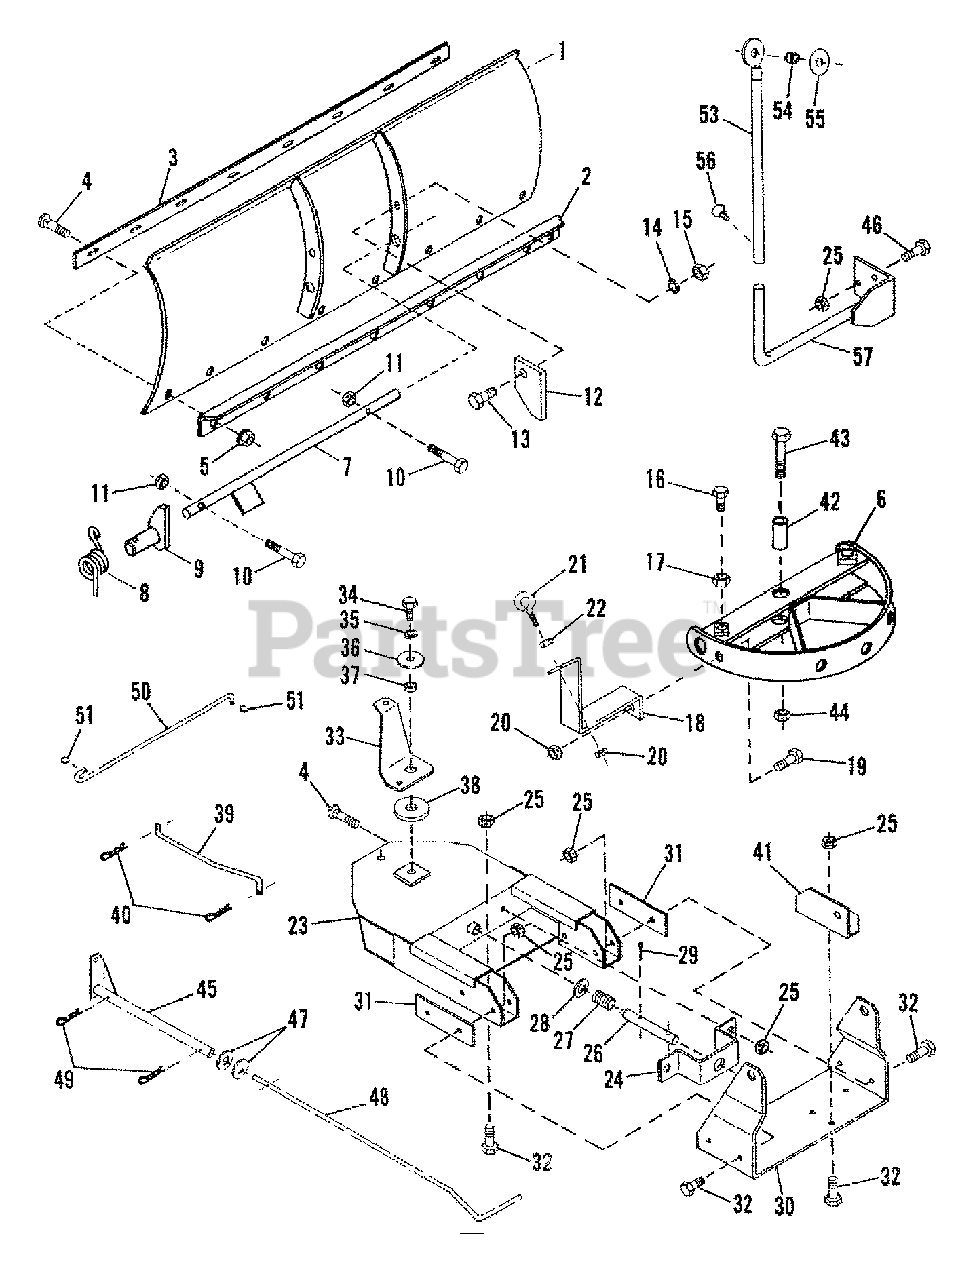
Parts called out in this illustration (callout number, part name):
1	Blade Assembly 46"
2	Blade Back up Angle 46"
3	Scraper Blade 46"
4	Bolt-5/16 x 3/4 Carriage
5	Nut-5/16-18 Serrated
6	Pivot Quadrant Assembly
7	Breakover Pin Assembly
8	Torsion Spring
9	Spring Anchor Assembly
10	Bolt-1/4-20 x 1-1/2 Hex Head
11	Nut Lock
12	Blade Stop Strap
13	Bolt-5/8-11 x 1-1/4
14	Washer-5/8" Med. Lock
15	Nut-5/8-11 Hex Jam
16	Bolt-1/2-13 x 1-1/2 Hex Head
17	Nut-1/2-13 Hex Jam
18	Pivot Control Bracket
19	Bolt-3/8-16 x 1" Hex Head
20	Nut-3/8-16 Hex Lock
21	Eye Bolt-3/8-16 x 2"
22	Nut-3/8-16 Lt. Hex
23	Pivot Bracket Assembly
24	Lock Pin Bracket
25	Nut-5/16-18 Hex Lock
26	Lock Pin
27	Coupler Spring
28	Washer-21/32 x 1-5/16
29	Cotter Pin-1/8" x 1-1/4"
30	Mounting Bracket
32	Bolt-5/16-18 x 1 Hex Head
33	Pivot Release Bracket
34	Bolt-3/8-16 x 3/4 Hex
35	Washer-3/8 Med. Lock
36	Flat Washer
37	Spacer
38	Flat Washer
39	Lock Pin Release Rod
40	Hair Cotter Pin
41	Lift Bracket
43	Bolt-1/2-13 x 3 Hex Head
44	Nut-1/2-13 Hex Lock
45	Pivot Control Arm
46	Bolt-5/15-18 x 3/4 Hex 3
47	Washer-19/32 x 1-3/16
48	Control Handle Rod
49	Hair Cotter Pin
50	Pivot Release Rod
51	Spring Clip
53	Control Support Assembly
54	Control Rod Guide Bushing
55	Angling Control Decal
56	Thumb Screw
57	Control Rod Support Assembly
